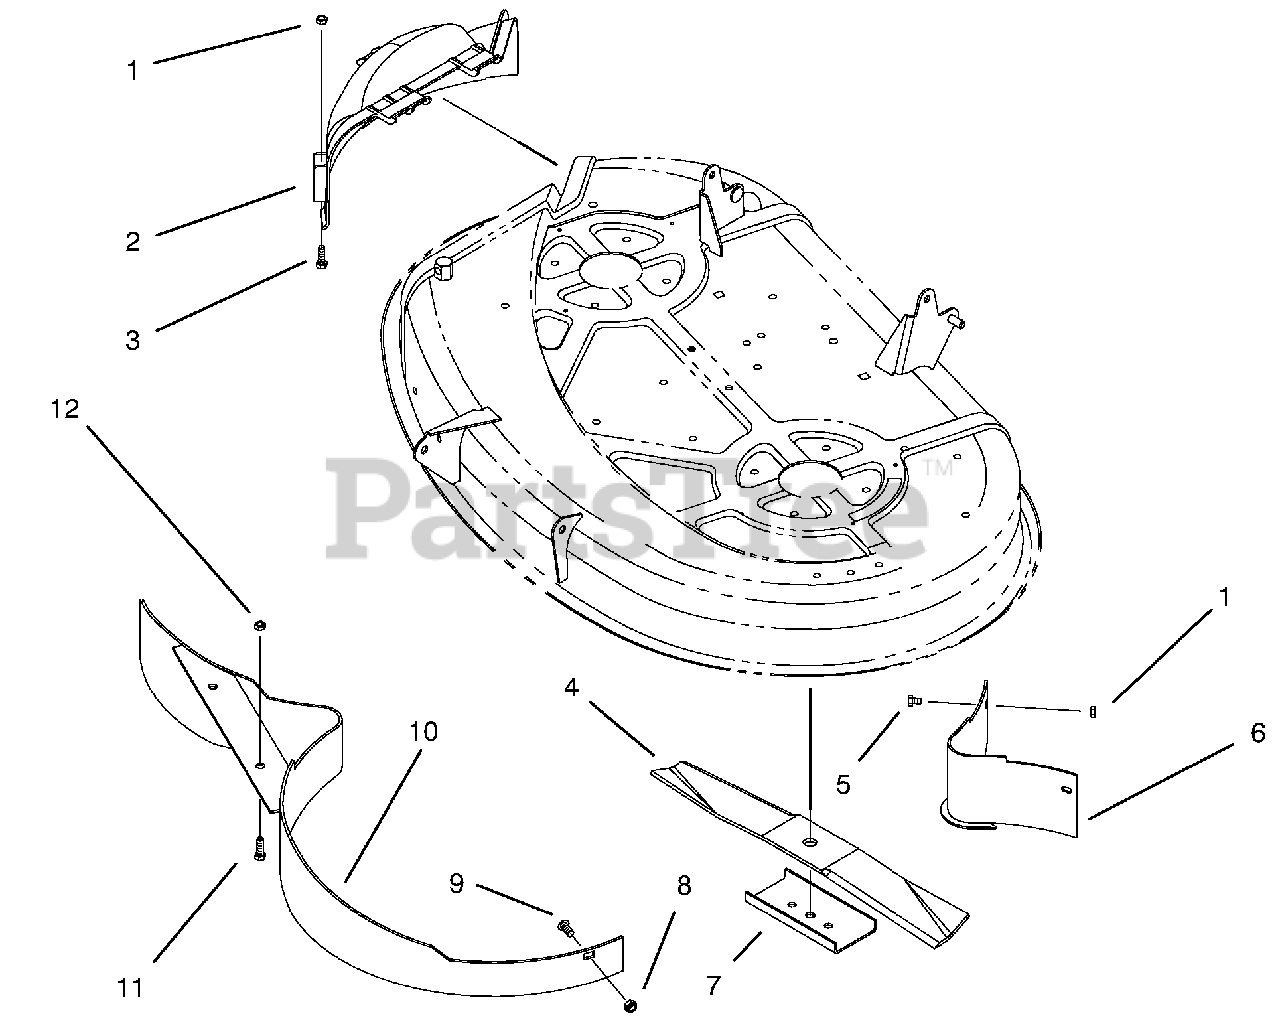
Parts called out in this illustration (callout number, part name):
1	Nut-Lock
2	Cover-Discharge
3	Screw-Hex Hd. Cap
4	Blade-Power Mulch
5	Screw-Hex Hd. Cap
6	Baffle-Rear
7	Stiffener-Blade
8	Nut-Lock
9	Bolt-Carriage
10	Baffle-Power Mulch
11	Screw-Hex Hd. Cap
12	Nut-Lock
